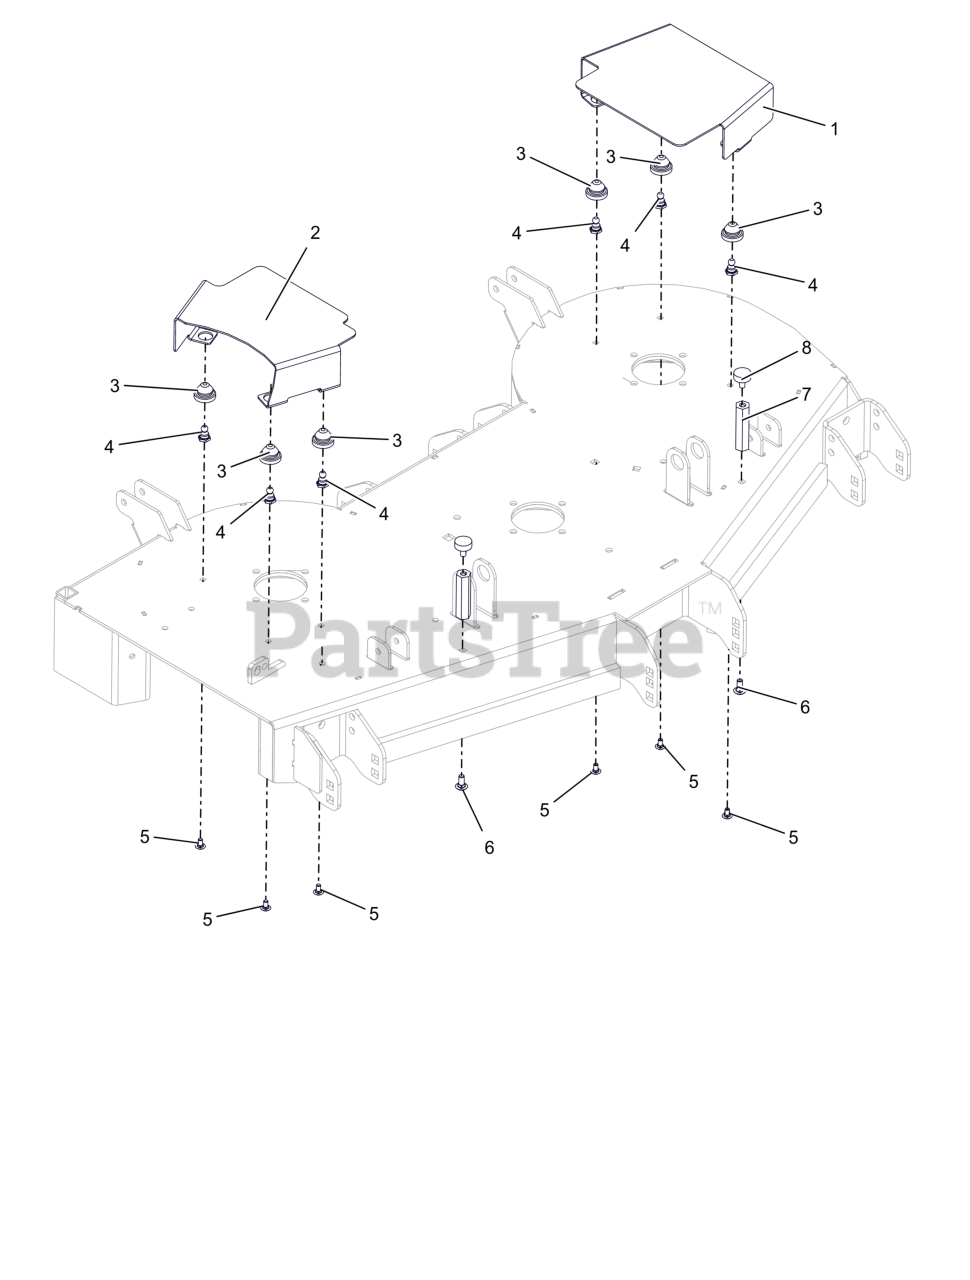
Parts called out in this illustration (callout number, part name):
1	GUARD, LH DECK BELT (RED)
2	GUARD, RH DECK BELT (RED)
3	COUPLING, RUBBER PUSH-IN
4	STUD, BALL FEMALE .250-20 THREAD
5	BLT, RHSSN.25-20X.500 G5 ZCC
6	BTL,RHSN .313-18 X 0.75 G5 ZCC LT
7	NUT, COUPLING .31-18 X 3.00
8	BUMPER, RUBBER
